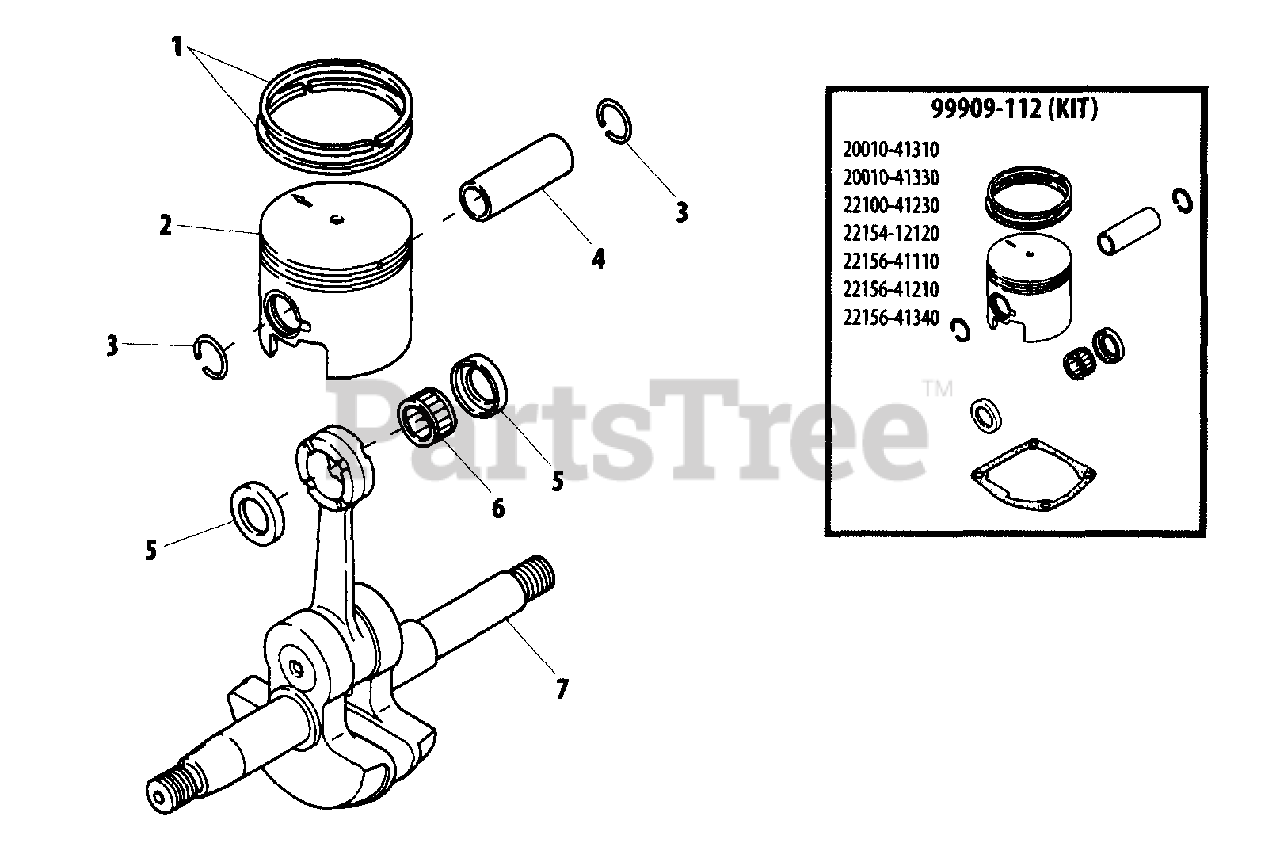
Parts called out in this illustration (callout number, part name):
1	RING, PISTON
2	PISTON
3	RING, RETAINING
4	PIN, PISTON
5	SPACER, PISTON
6	BEARING, NEEDLE
7	CRANKSHAFT ASSY
99909-112	PISTON ASSY
